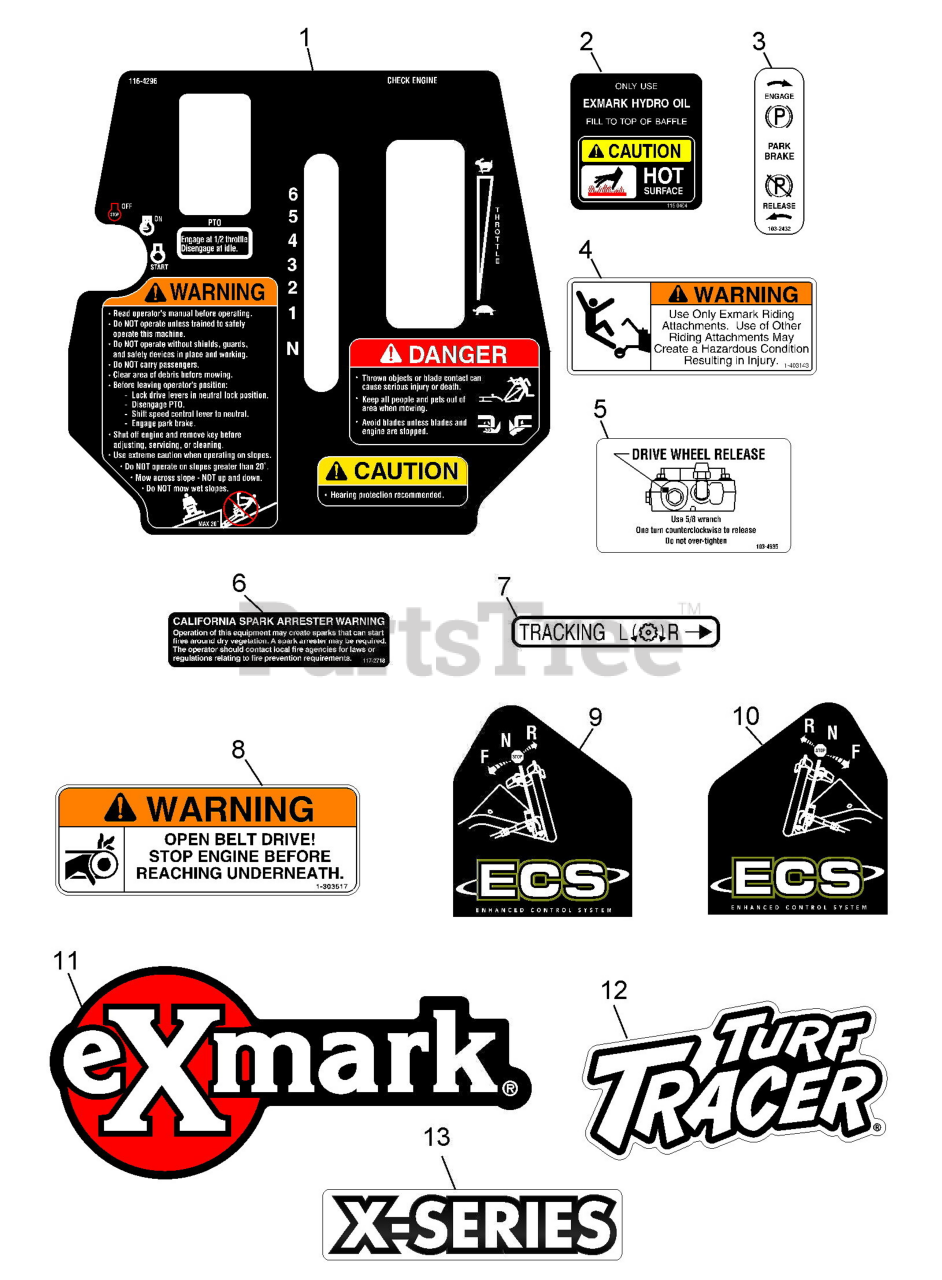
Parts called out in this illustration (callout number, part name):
1	DECAL,CONSOLE TTX
2	DECAL-HYDRAULIC TANK
3	DECAL,PARKING BRAKE
4	DECAL,SULKY WARNING
5	DECAL,DRIVE RELEASE
6	DECAL-ARRESTER, SPARK
7	DECAL,TRACKING ADJUST
8	DECAL,BELT DRIVE
9	DECAL,LH ECS INSTRUCTION
10	DECAL,RH ECS INSTRUCTION
11	DECAL,EXMARK LOGO
12	DECAL,TTH MODEL
13	DECAL-X-SERIES
